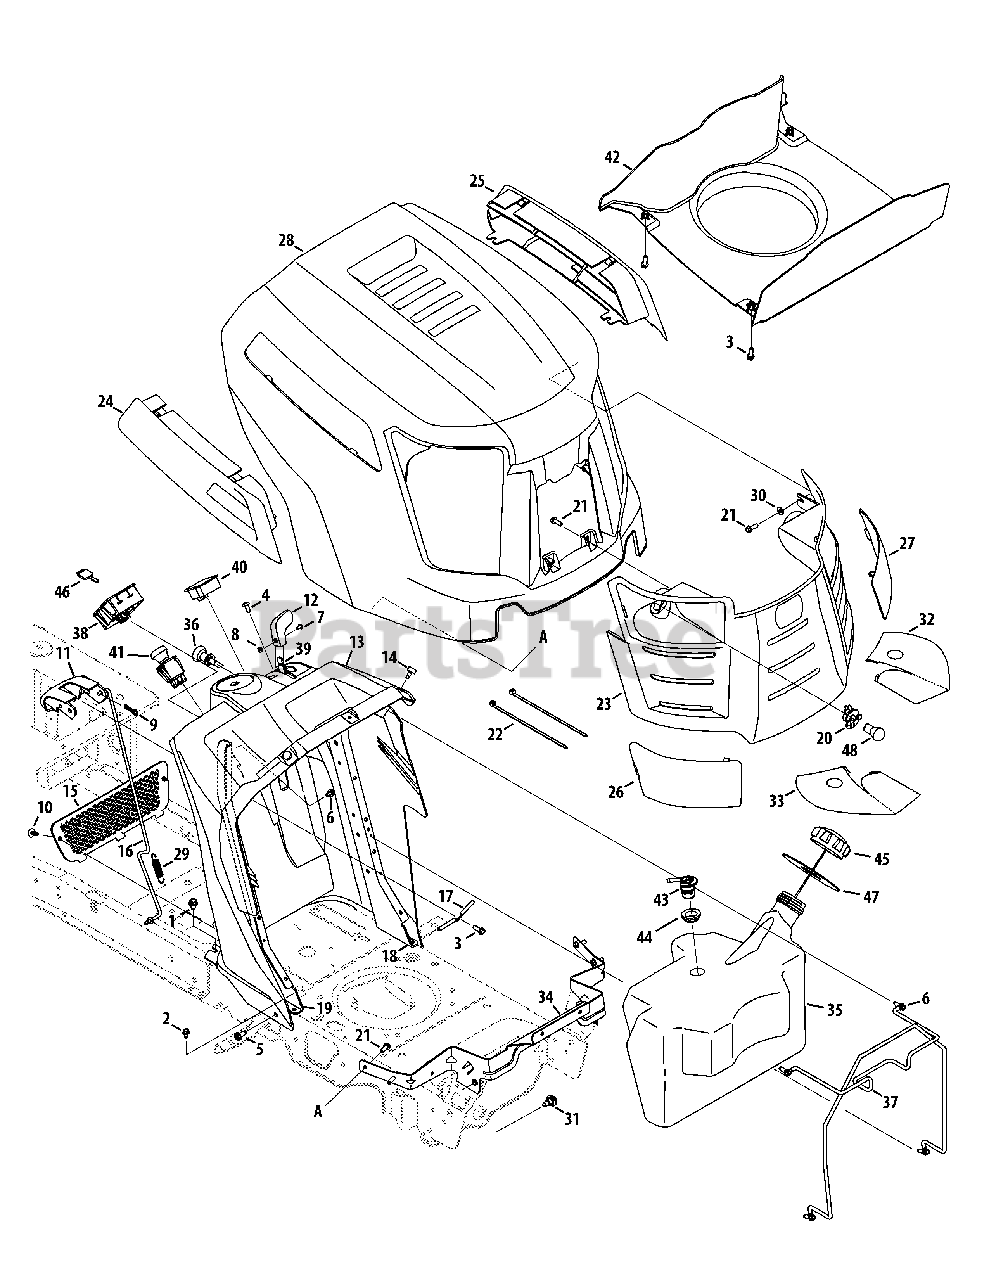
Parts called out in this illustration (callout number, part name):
1	Screw, Self-tapping, 5/16-18, .750
2	Screw, Self-tapping, 1/4-20, 0.500
3	Screw, HL, 1/4-15, 0.750
4	Screw, Ab, 1/4-14, 0.625,
5	Screw, Self-tapping, 5/16-18, 0.750,
6	Screw, Self-tapping, 1/4-20 x .625
7	Screw, Mach, #8-32, 0.375
8	Nut, Hex, #8-32
9	Pin, Cotter, Bow-Tie 72
10	Clip, Ratchet, .250 Dia
11	Lever, Dash, Cruise/Brake
12	Knob, Throttle
13	Dash Panel, A-Style, Elect PTO
14	Bumper, .62 Dia X .3
16	Rod, Control, Latch Cub
17	Rod, Lever, Bent
18	Support, Dash, Plate LH
19	Support, Dash, Plate RH
20	Socket, Lamp
21	Screw, 1/4 Dia, .750
22	Tie, Cable, Push Mount 7.5 Lg
23	Grille Ass’y (Incl. 26, 27, 32 & 33)
24	Scoop, Hood, RH A-Style
25	Scoop, Hood, LH A-Style
26	Lens, Hood, RH A-Style
27	Lens, Hood, LH A-Style
28	Hood, A-Style
29	Spring, .500 Dia. x 2.733
30	Washer, Flat, .271, .630, .065
31	Screw, Shoulder, .43x.29, 5/16-18
32	Reflector, Cub A Style, LH
33	Reflector, Cub A Style, RH
34	Bracket, Pivot, Hood A-Style
35	Tank, Fuel, 3.30 Gal.
36	Control, Choke, 40.5 x 2, Yellow
37	Rod, Support, Fuel Tank
38	Module Switch, Ignition
39	Cable, Throttle, 39"
40	Meter, Indicator
41	Switch, Electric PTO, Yellow
42	Plenum, A-Style, B&S Intek Twin
43	Valve, Rollover Grommet
44	Grommet, Rubber, 23.0 ID
45	Cap, Fuel
46	Key, Assembly
47	Gasket, Fuel Tank
48	Lamp, 12v
